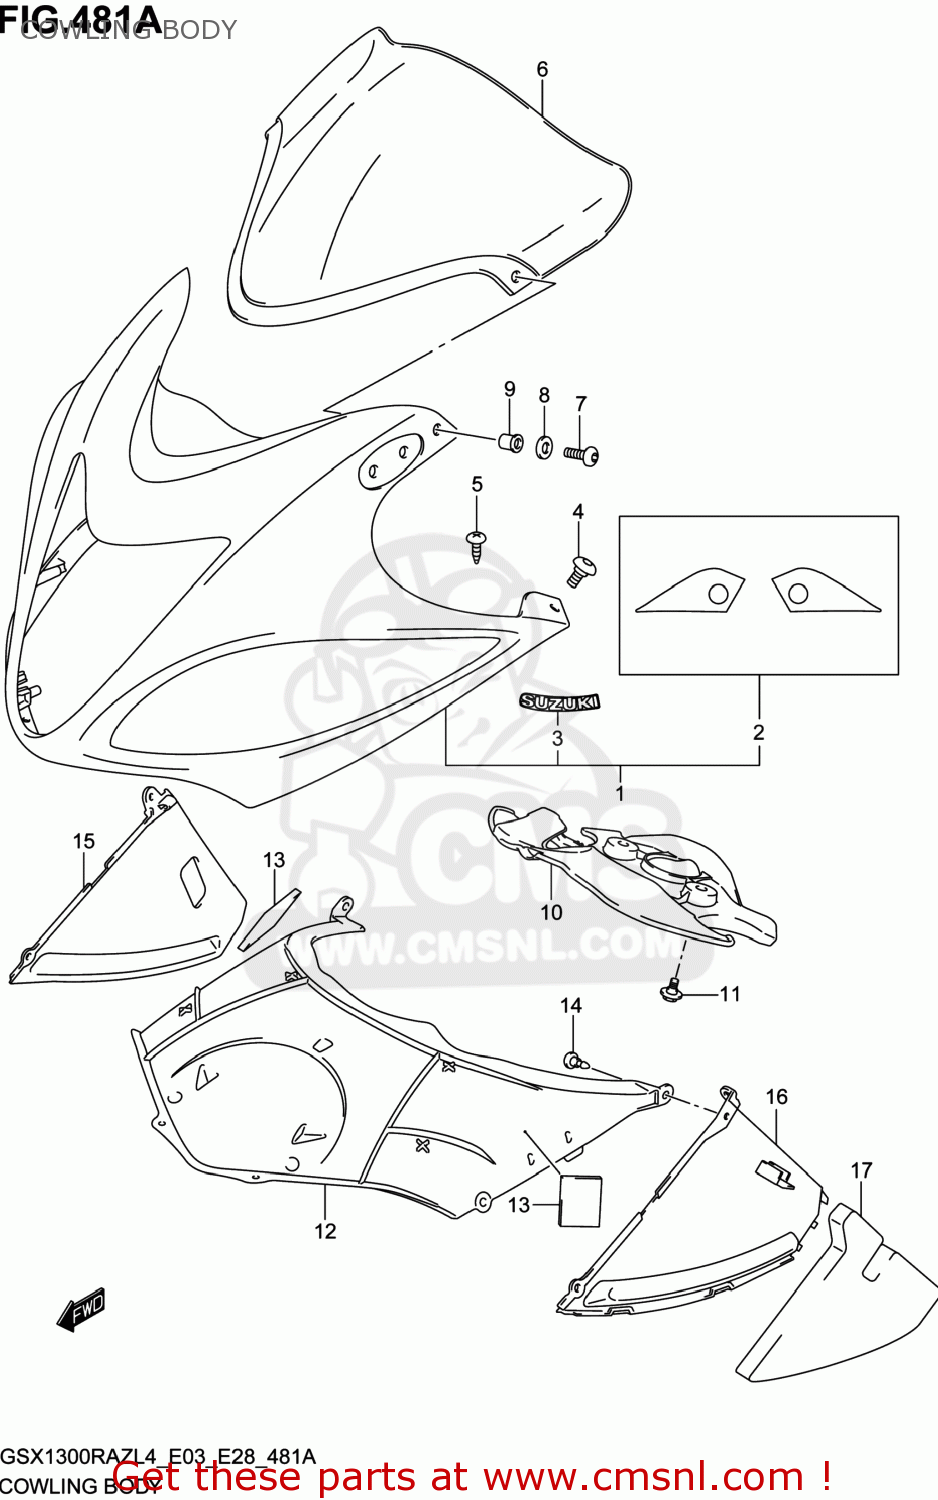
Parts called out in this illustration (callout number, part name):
1	COWLING ASSY,BODY
2	TAPE SET,BODY COWLING
3	EMBLEM,SUZUKI
4	SCREW(5X16)
5	SCREW(5X16)
6	WINDSCREEN
7	SCREW(5X14)
8	WASHER
9	NUT
10	COVER,LWR BRACKET
11	BOLT(6X12)
12	COVER,BODY COWLING
13	COVER
14	CLIP(BLACK)
15	COWLING,UNDER INNER,R
16	COWLING,UNDER INNER,L
17	CUSHION,INNER COWL,L
